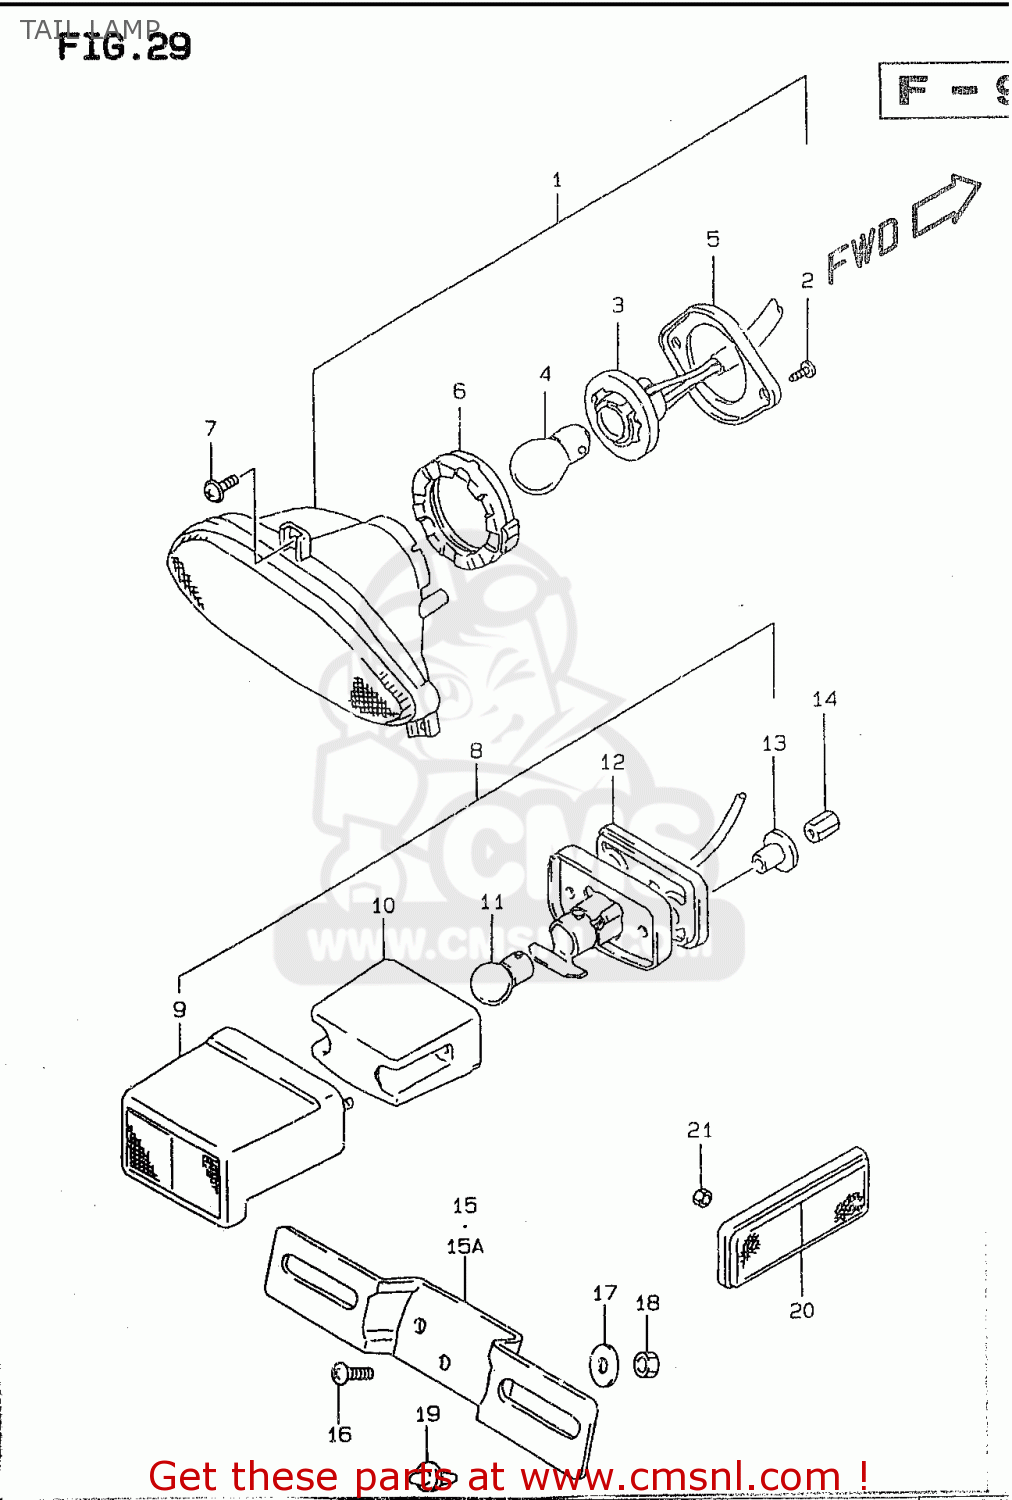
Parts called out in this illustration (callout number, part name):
1	LAMP ASSY,RR COMBINATION
2	SCREW
3	SOCKET & CORD
4	BULB(12V21/5W)
5	PLATE NO.2
6	CUSHION
7	TPG SCREW
8	LAMP ASSY,LICENSE PLATE
9	COVER,LENS
10	LENS
11	BULB(12V5W,BF150-40160A)
12	CUSHION
13	SPACER
14	NUT
15	BRACKET,LICENSE PLATE
15A	BRACKET,LICENSE PLATE
16	SCREW 6X12
17	WASHER(6.5X20X1.6)
18	NUT 6MM
19	CUSHION
20	REFLEX REFLECTOR,FR SIDE
21	NUT
